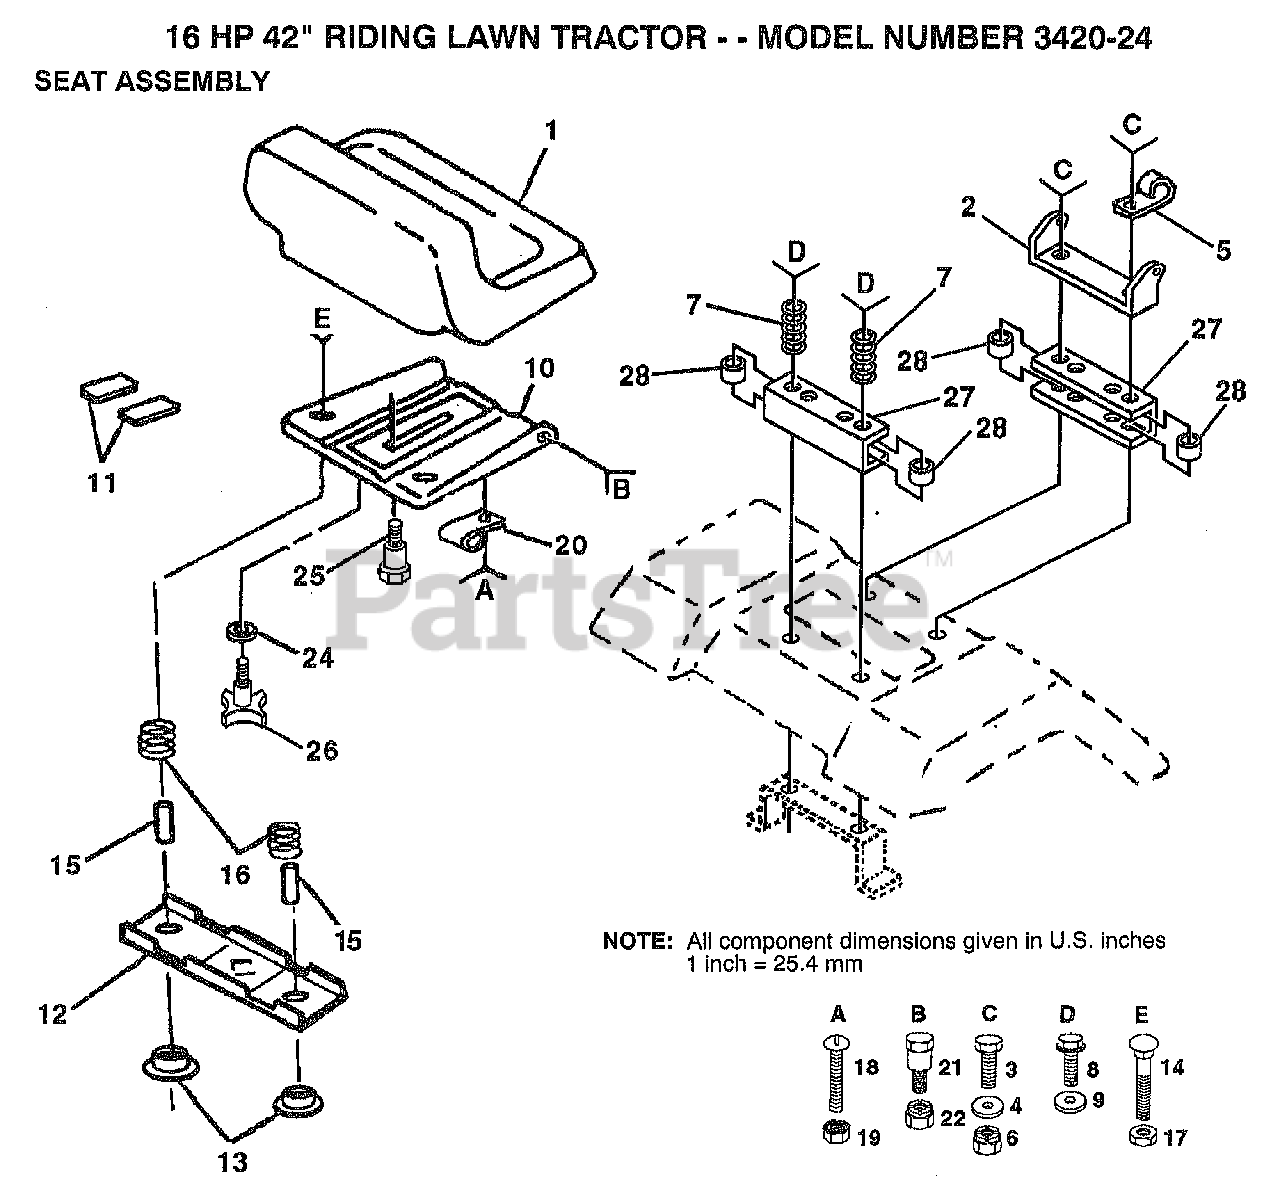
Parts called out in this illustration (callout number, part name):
3	BOLT
4	WASHER
5	CLIP T
7	SPRING COMPRESSIO
8	SCREW
9	WASHER
11	STRIP FORM
12	BRKT SWITCH
13	BUSHING
15	SPACER SPLIT
16	SPRING COMPRESSED
19	"NUT,KEPS"
24	WASHER
25	"BOLT,SHOULDER"
26	"KNOB 1/2"" YT"
27	SEAT SPACER
28	SPLIT SPACER
